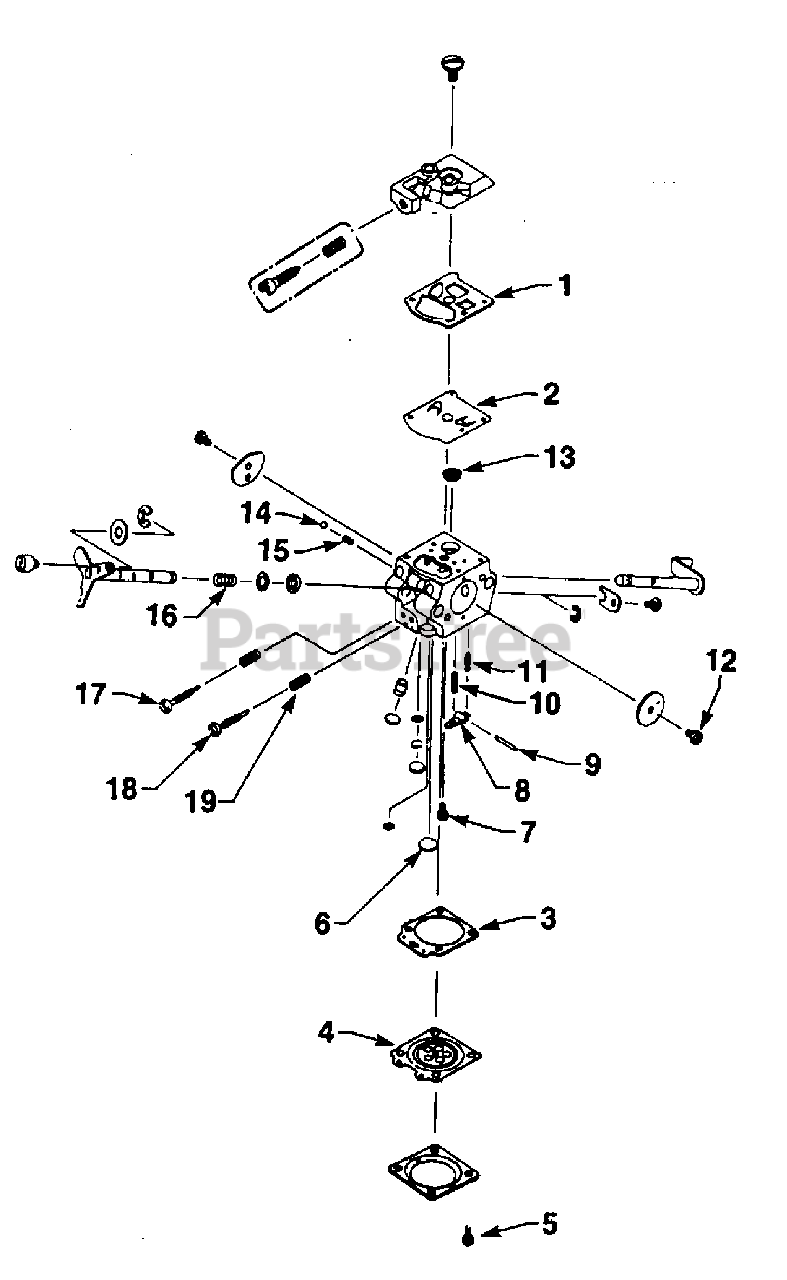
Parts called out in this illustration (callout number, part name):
1	Repair Kit
2	Repair Kit
3	Repair Kit
4	Repair Kit
5	Repair Kit
6	Repair Kit
7	Repair Kit
8	Repair Kit
9	Repair Kit
10	Repair Kit
11	Repair Kit
12	Repair Kit
13	Repair Kit
14	Repair Kit
15	Repair Kit
16	Repair Kit
17	Repair Kit
18	Repair Kit
19	Repair Kit
